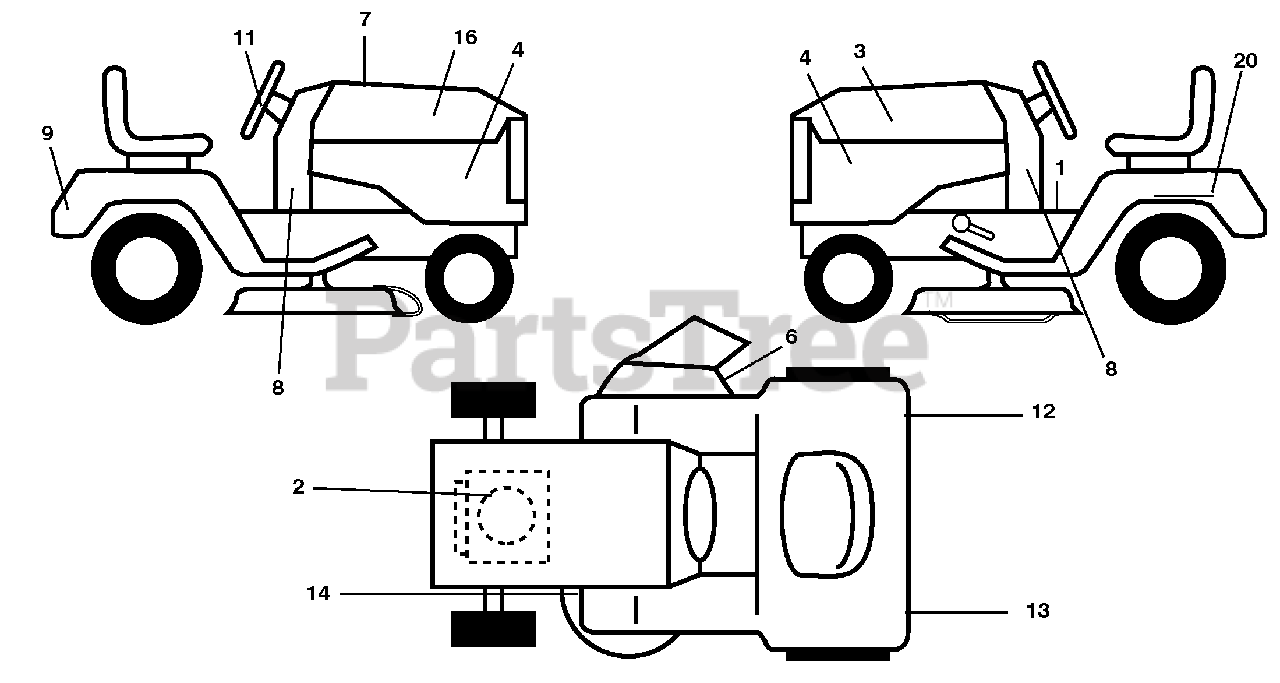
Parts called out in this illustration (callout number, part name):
1	Decal Oper. Warning
2	Decal Engine H.P.
3	Decal Hood LH
4	Decal Side Panel
6	Decal Warning, Keep Hand Away
7	Decal Replacement Parts
8	Decal LWRDASH
9	Decal Fender Logo
11	Decal Ins Strg Whl
12	Decal Fender SD RH
13	Decal Fender SD LH
14	Decal V-Belt Schematic
16	Decal Hood Rh
20	Decal Bat Dan/Psn
20	Pad Footrest LH
20	Pad Footrest RH
20	Decal Bypass
20	Manual Operator's E&F
20	Manual Parts
